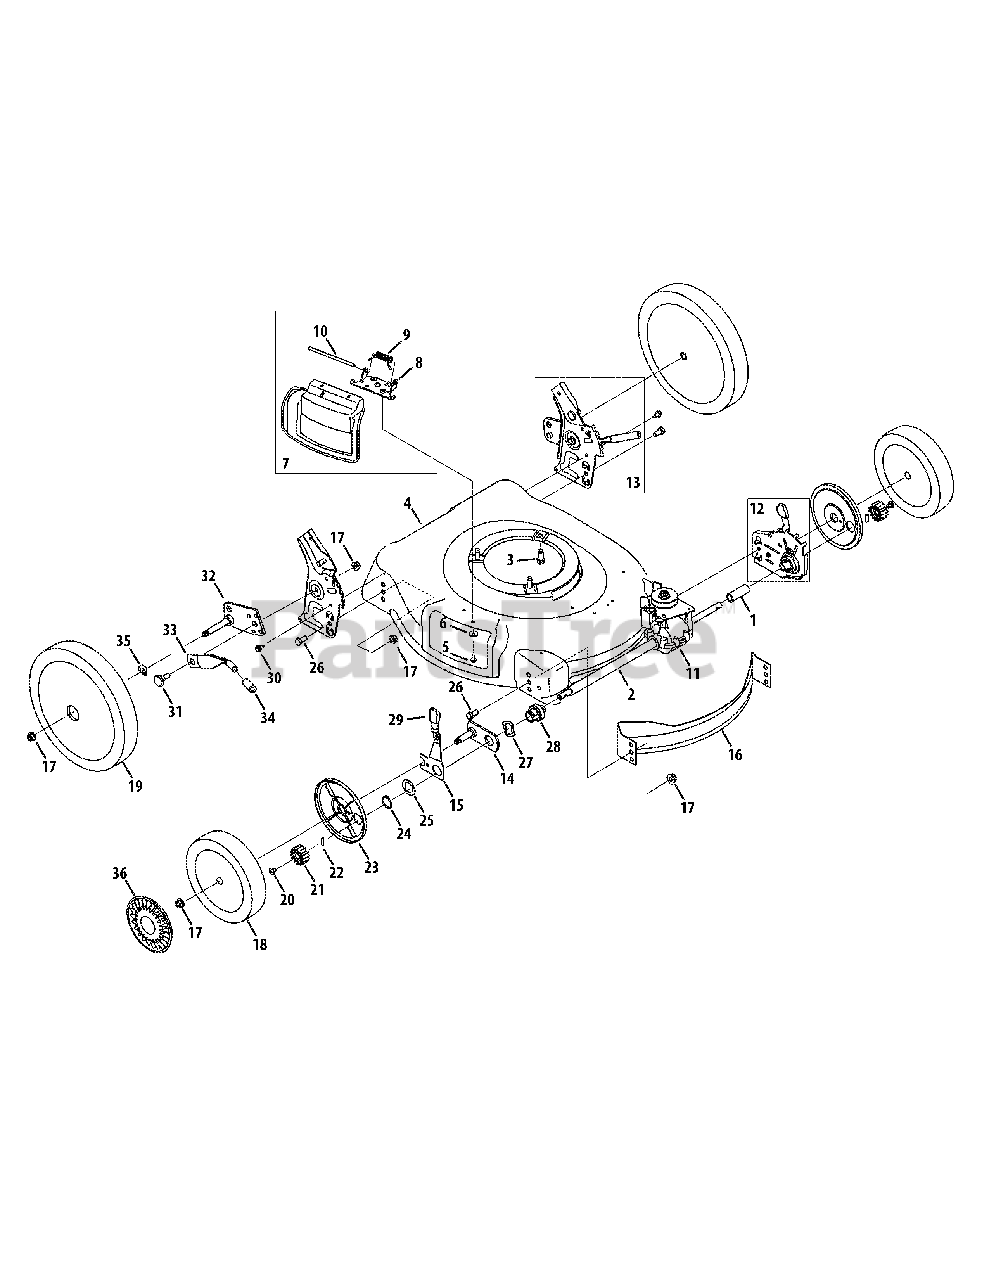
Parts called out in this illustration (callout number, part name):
1	Sleeve Spacer, 1.8" Lg.
2	Sleeve Spacer, 9.10" Lg.
3	TT Screw
4	21" Deck
5	TT Screw, 1/4-20 x 0.5
6	Bell Washer
7	Hinged Mulch Plug Assembly
8	Chute Deflector Adapter
9	Torsion Spring
10	Hinge Pin
11	Transmission Assembly
12	Height Adj. Assembly - LH
12	Height Adj. Assembly - RH
13	Handle Bracket Assembly - LH
13	Handle Bracket Assembly - RH
14	Pivot Plate Assembly
15	Front Lever - RH
15	Front Lever - LH
16	Front Baffle
17	Flange Lock Nut, 3/8-16
18	Front Wheel, 8 x 2.125
19	Rear Wheel, 12 x 2.125, Gray
20	Screw, 1/4-20 x .390
21	Gear 14T FWD - RH
21	Gear 14T FWD - LH
22	Dowel Pin
23	Wheel Dust Cap
24	Snap Ring
25	Flat Washer
26	Hex Screw, 3/8-16 x .75
27	Wave Washer
28	Bearing Assembly
29	Adjustment Knob
30	TT Screw w/washer, 1/4-20 x .625
31	Shoulder Screw, .500 Dia. x .385
32	Pivot Arm Assembly - RH
32	Pivot Arm Assembly - LH
33	Rear Spring Lever
34	Foam Grip
35	Washer, Spring, .500 x 1.00 x .022
36	Hubcap
